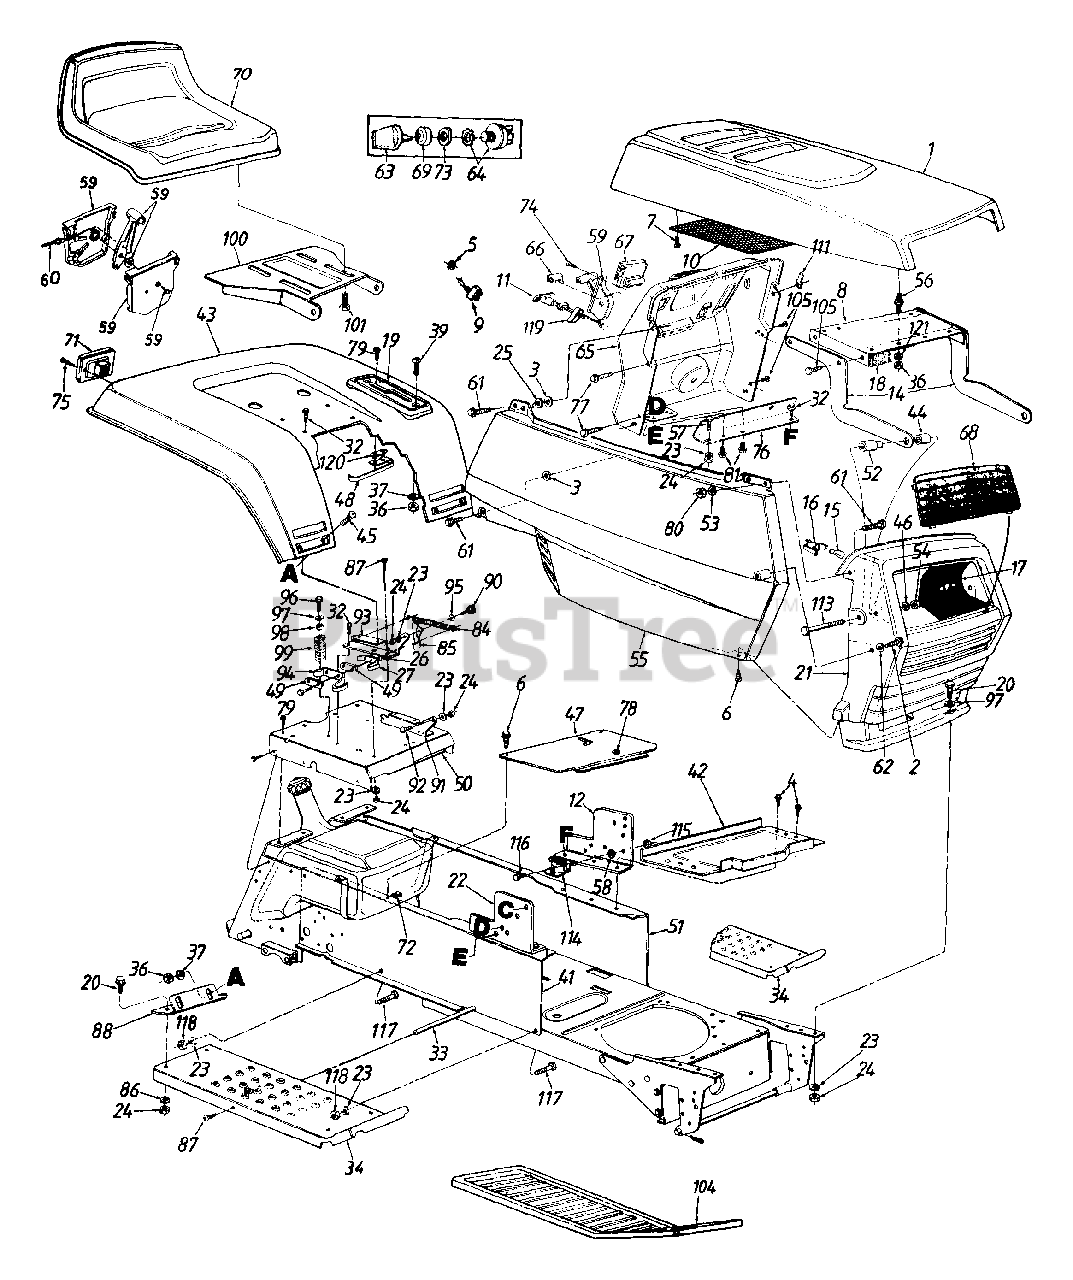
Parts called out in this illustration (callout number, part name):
1	Hood
2	Hex Wash. B-Tap Scr. 1/4 x .62" Lg.
3	Bolt Retainer 1/4" I.D.
4	Hex AB-Tap Scr. 1/4 x .62" Lg.
5	Hex Nut 1/2-27 Thd.
6	Truss Mach. B-Tap Scr. #10 x .5" Lg.
7	Hex Wash Hd. AB-Tap Scr. #8 x .5" Lg.
11	Choke Control
12	Dash Support Brkt. - L.H.
16	Twist Lock - Lamp Socket
17	Reflector - Headlight
19	Speed Control Index Brkt.
20	Hex Bolt 5/16-18 x 1.0" Lg.
21	Grille
24	Hex Nut 5/16-18 Thd.
25	Fl-Wash. 1/4" I.D. x .93" O.D.
26	Insulator Boss Plate
27	Seat Spring Switch
32	Hex Wash. Hd. AB-Tap Scr. 5/16 x .75" Lg.
33	Running Board Rod
37	L-Wash. 1/4" I.D.
39	Truss Mach. Scr. 1/4-20 x 1.0 Lg.
41	R.H. Side Frame
42	Battery Plate
45	Carriage Bolt 1/4-20 x .50" Lg.
46	Fl-Wash. .328" I.D. x .68" O.D.
49	Insulator Plate
52	Shld. Spacer .33" I.D.
53	Fl-Wash. .281" I.D. x .5" O.D.
54	Hex Cent. L-Nut 5/16-18 Thd.
55	Side Cover Ass'y. - R.H.
56	Double Ended Stud 1/4-20 Thd.
57	Hex Bolt 5/16-18 x .75" Lg.
58	Ext. L-Wash. 1/4" I.D.
59	Throttle Control Box Ass'y.
60	Throttle Control Wire 35" Lg.
61	Hex Bolt 1/4-20 x .62" Lg.
62	Fl-Wash. .281" I.D. x .73" O.D.
64	Ignition Switch
65	Dash Panel
66	Light Switch
67	Ammeter
68	Lens
69	Ignition Switch Cap
70	Seat Ass'y.
71	Taillight Ass'y.
72	Speed Nut #10Z
73	Ignition Switch Nut
74	Truss Mach. AB-Tap Scr. #10 x .5" Lg.
75	Truss Hd. AB-Tap Scr. #6 x .62"
78	Snap Bushing
79	Hex Wash. Hd. AB-Tap Scr. #8 x .50" Lg.
80	Hex L-Nut 1/4-20 Thd.
81	Hex Wash. Hd. B-Tap Scr. 5/16-18 x .5" Lg.
84	Ext. Spring 5.31" Lg.
85	Seat Lift Brkt.
86	Bell-Wash. .345" I.D. x .88" O.D.
87	Truss Machine Scr. 5/16-18 x .75" Lg.
95	Spr. - Wash. .445" I.D.
96	Torx Hd. Tap Scr. 5/16-18 x .75"
97	Fl-Wash. .344" I.D. x 1" O.D.
99	Compression Spring
101	Hex Tap Scr. 3/8-16 x .75"
105	Hex Tap Scr. 1/4-20 x .5" Lg.
111	Speed Nut 1/4-20 Thd.
113	Hex Bolt 5/16-18 x 2.75"
114	Solenoid
115	Hex Sems Nut 1/4-20 Thd.
116	Hex Bolt 1/4-20 x .5" Lg.
117	Rib Neck Bolt 5/16-24 x .75" Lg.
118	Hex Nut 5/16-24 Thd.
119	Retainer Clip
120	Insulator Nut Plate
121	Bell-Wash. .265" I.D. x .75" O.D.
